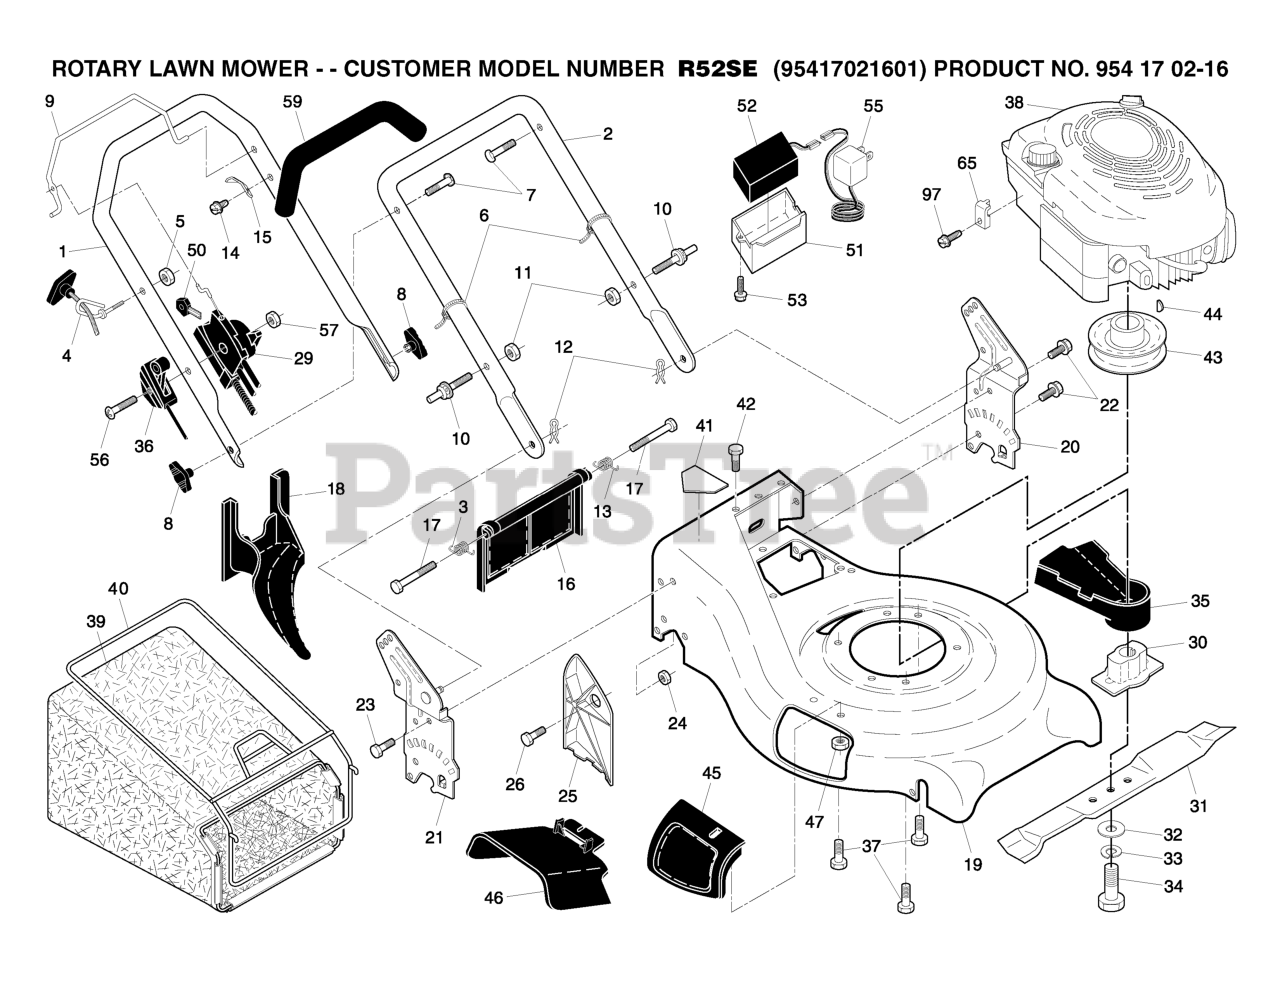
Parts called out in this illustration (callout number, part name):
1	HANDLE.UP.DLX.COMF.W/GRIP.GREY
2	HANDLE LOWER
3	SPRING.LH.REAR.DOOR.21.RWGD
4	ROPE, GUIDE
5	NUT
6	TIE GUIDE
7	BOLT, HANDLE 5/16-18X1.75
11	NUT.CENTERLOCK.5/16-
12	HAIRPIN COTTER
13	SPRING.RH.REAR.DOOR.21.RWGD
14	BRACKET UPSTOP
16	DOOR.REAR.PLASTIC.21.RWGD.BLAC
18	PLUG, MULCHER
20	BRKT.ASM.HNDL.21.RWGD.LT
21	BRKT.ASM.HNDL
22	SELF-TAPPING SCREW 5/16-18X3/4
23	BOLT, HEX HEAD 5/16-18
24	NUT.71038.31-18.HEX.NYLOCK
25	CLIPPING DEFLECTOR
29	CONTROL.COMBI.KEY.ASMR
30	ADAPTER.BLADE
32	WASHER,HARDEN
33	LOCKWASHER
34	SCREW, HEX HD 3/8-24 X 1-3/8
36	CONTRL.THROTTLE.
37	BOLT 3/8-16X1-1/8
40	GRASS CATCHER FRAME
41	DECAL.INTERNATIONL.CUTFINGER
43	PULLEY.ENG.25MMM
44	HI-PRO KEY
45	MULCHER DOOR ASM.
46	DEFLECTOR, DISCHARGE
50	KEY.MOLDED
51	BOX.BATTERY.21RD.,RWGD
52	BATTERY WITH AMP CONECTOR AGM
53	SCREW.HX.13X.750
55	CHARGER.BATTERY.CE
56	BATTERY
59	GRIP.HANDLE.FOAM
65	CABLE CLAMP(ENGINE)
97	SCREW.HEX.HEAD.WASHER.10-16
